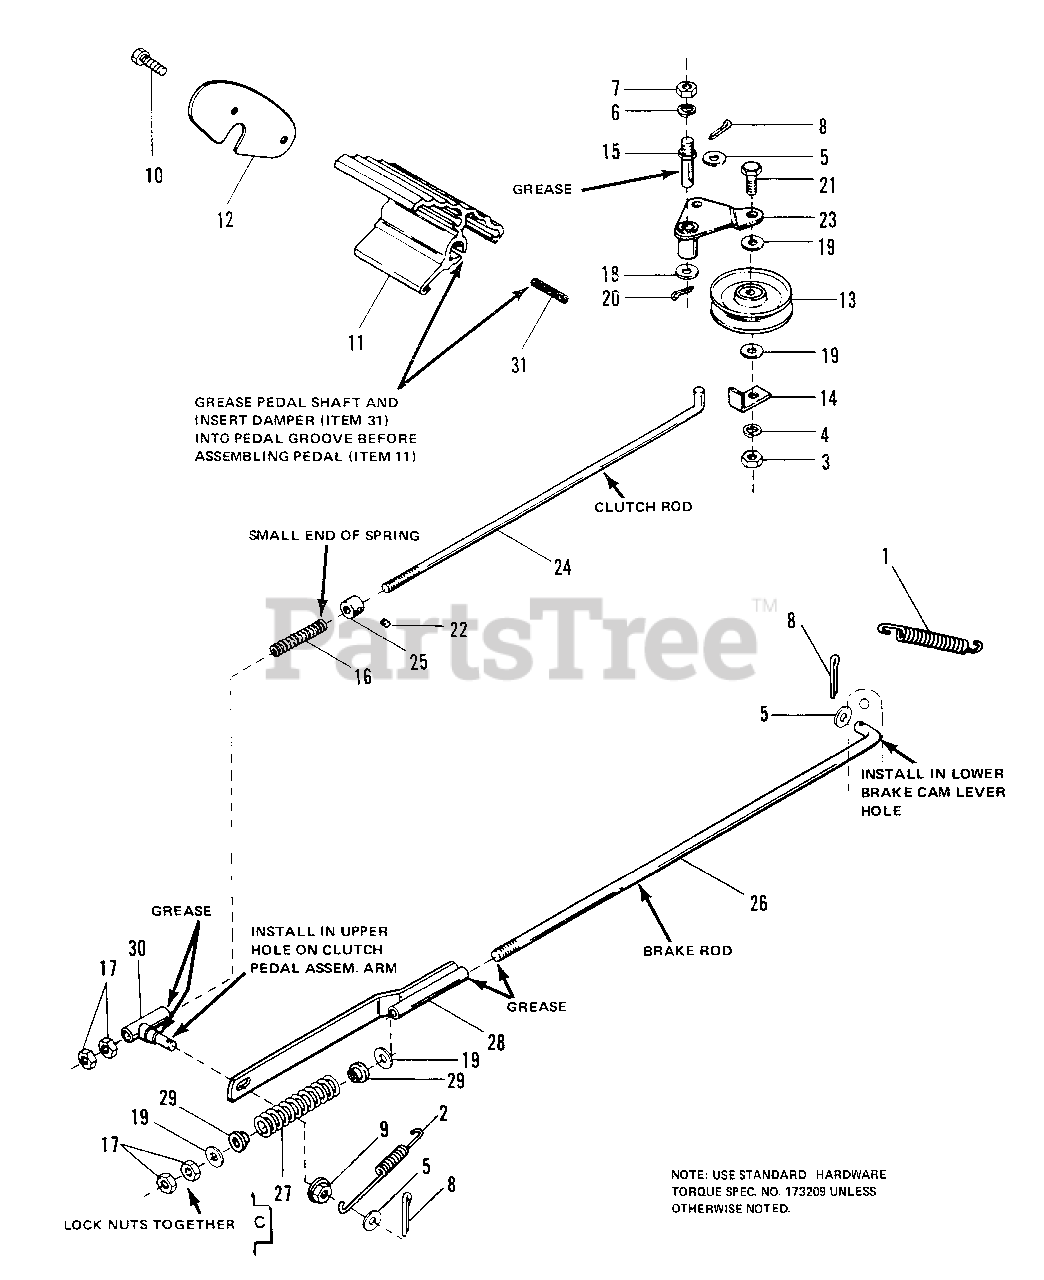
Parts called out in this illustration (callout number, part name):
1	SPRING, Tension
2	SPRING, Return
3	NUT, Hex, 3/8-16
4	LOCKWASHER, Spring, 3/8
5	WASHER, Plain, 1/4
6	LOCKWASHER, Spring, 7/16
7	NUT, Hex, 7/16-14
8	PIN, Cotter, 3/32 x 3/4
9	LOCKNUT, Flange, 5/16-18
10	SCREW, Hex Washer, 1/2-20 x 5/8
11	PEDAL, Foot
12	PLATE, End
13	PULLEY, Idler
14	GUIDE, Belt
16	SPRING, Compression
17	NUT, Hex, 5/16-18
18	WASHER, Plain, 3/8
19	WASHER, Plain, 5/16
20	PIN, Cotter, 1/8 x 3/4
21	CAPSCREW, Hex Hd., 3/8-16 x 1-1/2
22	SCREW, Set, 1/4-20 x 3/8, Gr. 8
23	IDLER ASSY
24	ROD, Clutch
25	COLLAR, Set
26	ROD, Brake
28	GUIDE ASSY, Rod
29	SUPPORT, Spring
30	GUIDE ASSY, Rod
